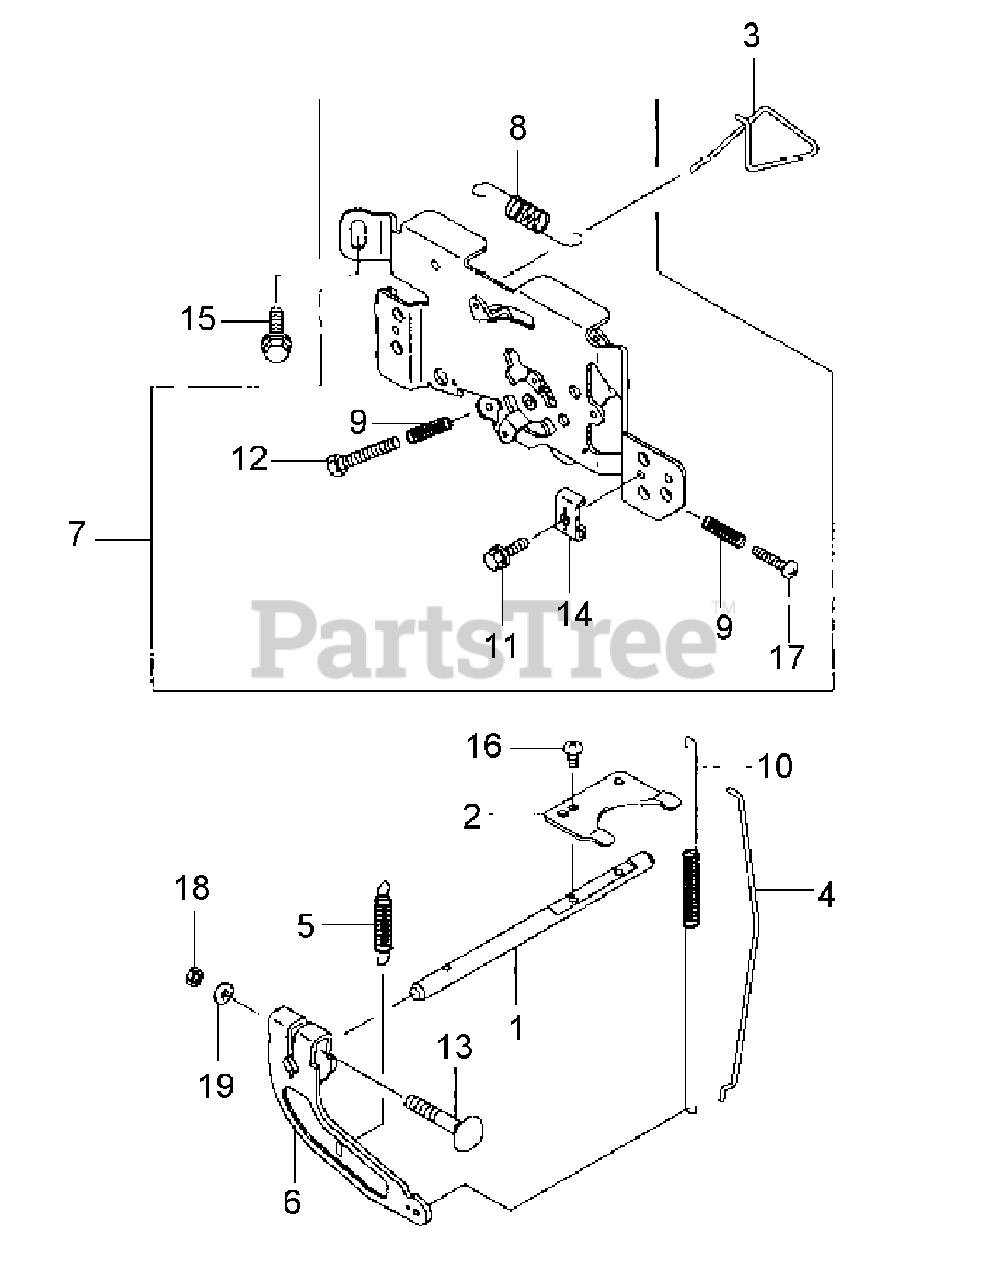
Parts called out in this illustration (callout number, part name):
1	SHAFT
3	CHOKE LINK
4	LINK
5	GOVERNOR SPRING
7	CONTROL PANEL
8	SPRING
13	BOLT, 6x35
15	FLANGED BOLT
19	PLAIN WASHER
